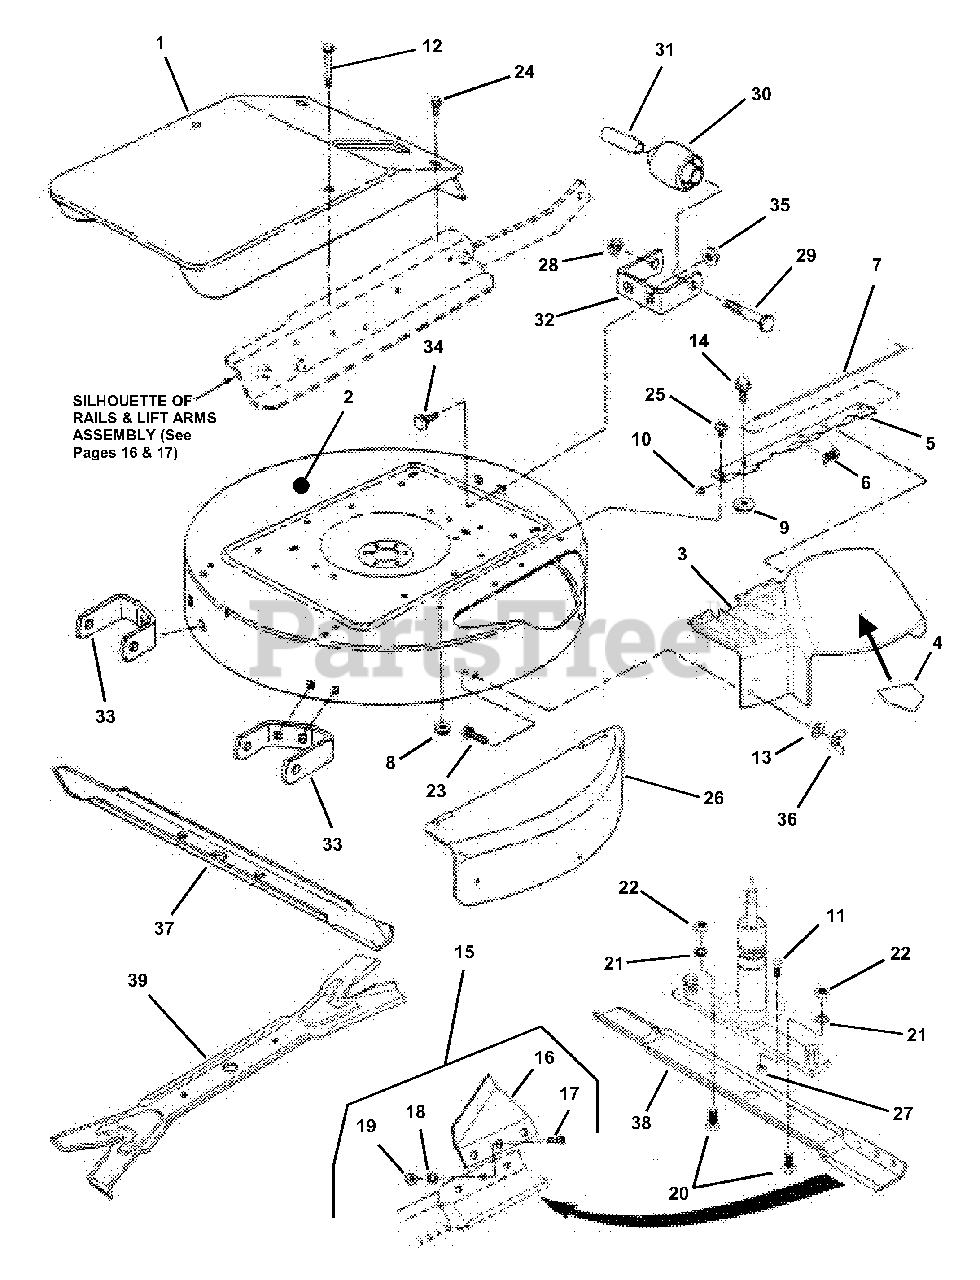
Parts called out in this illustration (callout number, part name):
1	COVER, Spindle
2	DECK, 28" Replacement (Painted deck with decals)
2	DECK, 33" Replacement (Painted deck with decals)
3	DEFLECTOR, Discharge (28" & 33" Deck)
4	DECAL, DANGER (Cut Finger)
5	HINGE, Deflector
6	SPRING, Hinge
7	PIN, Hinge
8	NUT, 5/16-18 Hex Flange Lock
9	NUT, 1/4-20 Hex Flange Lock
10	NUT, Push
11	BOLT, 3/8-16 x 3/4" Hex Flange Lock
12	SCREW, 1/4-20 x 3-1/2" Hex Washer Self-Tap, Gr. 5
13	WASHER, 5/16 Flat
14	BOLT, 1/4-20 x 1/2" Hex Flange Lock
15	AIR LIFT KIT, Hi-Vac
16	AIR LIFT, Hi-Vac (3 hole)
17	SCREW, 5/16-24 x 11/16" Machine
18	WASHER, 5/16-24 Internal Tooth Lock
19	NUT, 5/16-24 Hex
20	SCREW, 1/2-20 x 1" Hex Head Cap, Grade 5
21	WASHER, 1/2 Internal Tooth Lock
22	NUT, 1/2-20 Hex Jam
23	BOLT, 5/16-18 x 3/4" Short Neck Carriage, Grade 5
24	SCREW, 1/4-20 x 5/8" Hex Self-Tap w/ Captured Washer
25	BOLT, 5/16-18 x 1/2" Hex Flange Lock
26	COVER, 28" Mulcher
26	COVER, 33" Mulcher
27	NUT, 3/18-16 Hex Flange Lock
28	NUT, 3/8-24 Hex Nyloc
29	SCREW, 38-24 x 3-3/4" Hex Head Cap, Grade 5
30	WHEEL, Gage
31	SPACER
32	BRACKET, Gage Wheel (Front)
33	BRACKET, Gage Wheel (Rear)
34	BOLT, 5/16-18 x 1/2" Short Neck Carriage, Grade 5
35	NUT, 5/16-18 Hex Flange Lock
36	NUT, 5/16-18 Wing
37	BLADE, 28" Mulcher
37	BLADE, 33" Mulcher
38	28" BLADE
38	33" BLADE
39	BLADE, Ninja, 28"
39	BLADE, Ninja, 33"
